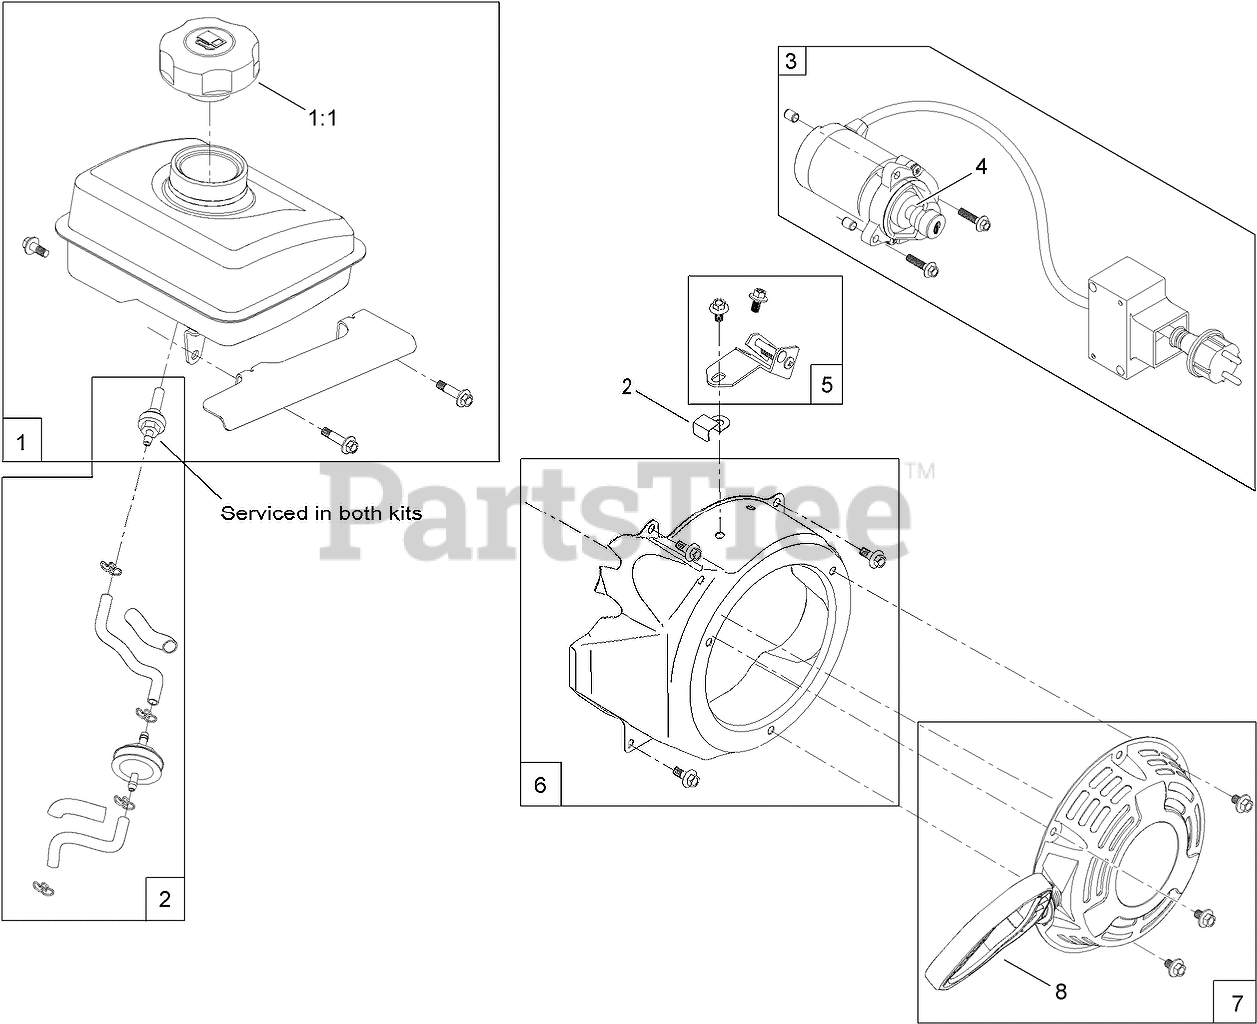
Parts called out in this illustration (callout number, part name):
1	FUEL TANK AND CAP KIT
1:1	CAP-FUEL
2	FUEL LINE KIT
3	ELECTRIC STARTER KIT
4	PINION KIT
5	GOVERNOR KIT
6	BLOWER SHROUD KIT
7	RECOIL ASM KIT
8	MITTEN GRIP KIT
